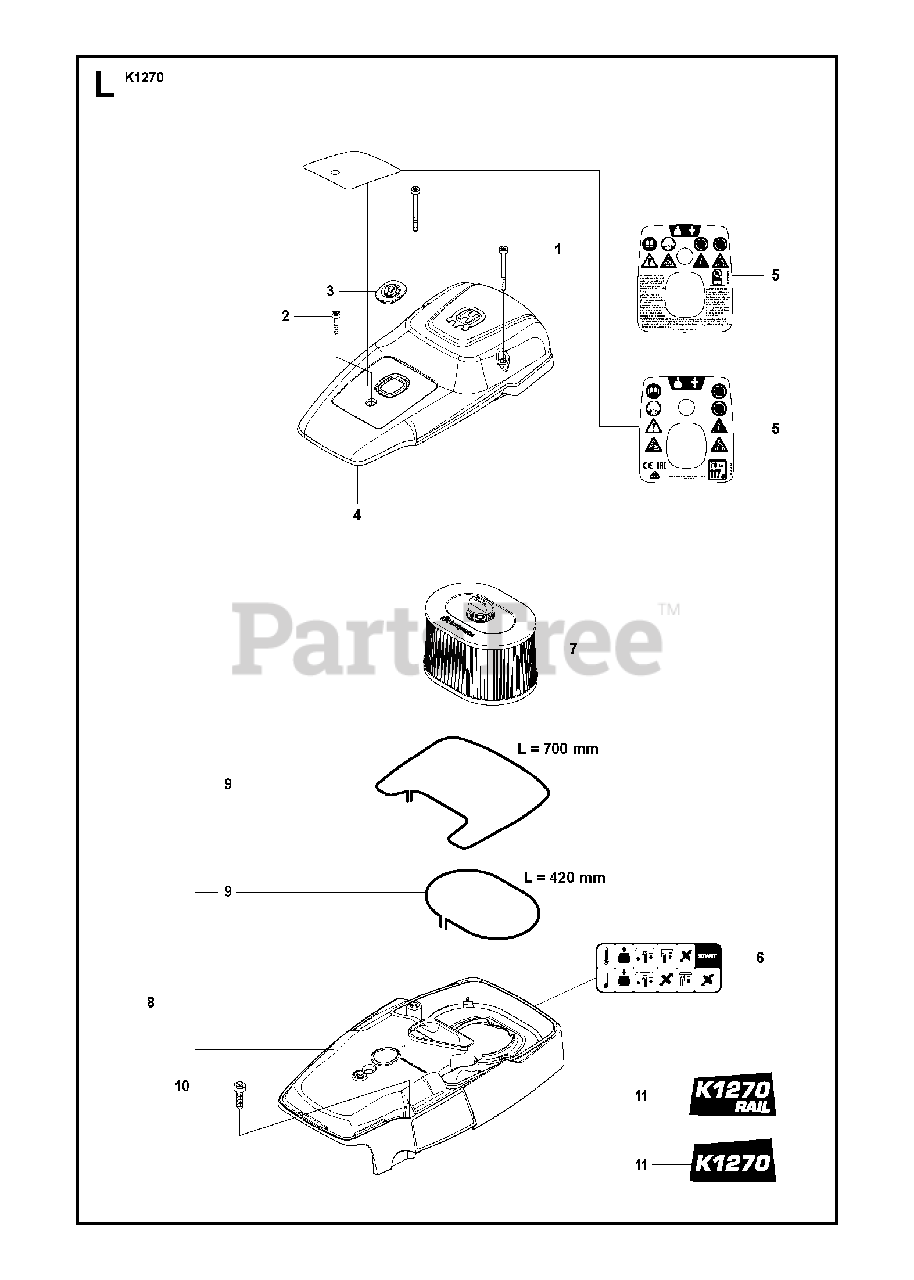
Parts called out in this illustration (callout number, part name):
1	SCREW ITXSCM
2	SCREW ITXSCM
5	DECALUSA, CANADA, MEXICO
7	AIR FILTERStandard
8	CYLINDER COVERIncl. 9 - 10
10	SCREW ITXSCM
